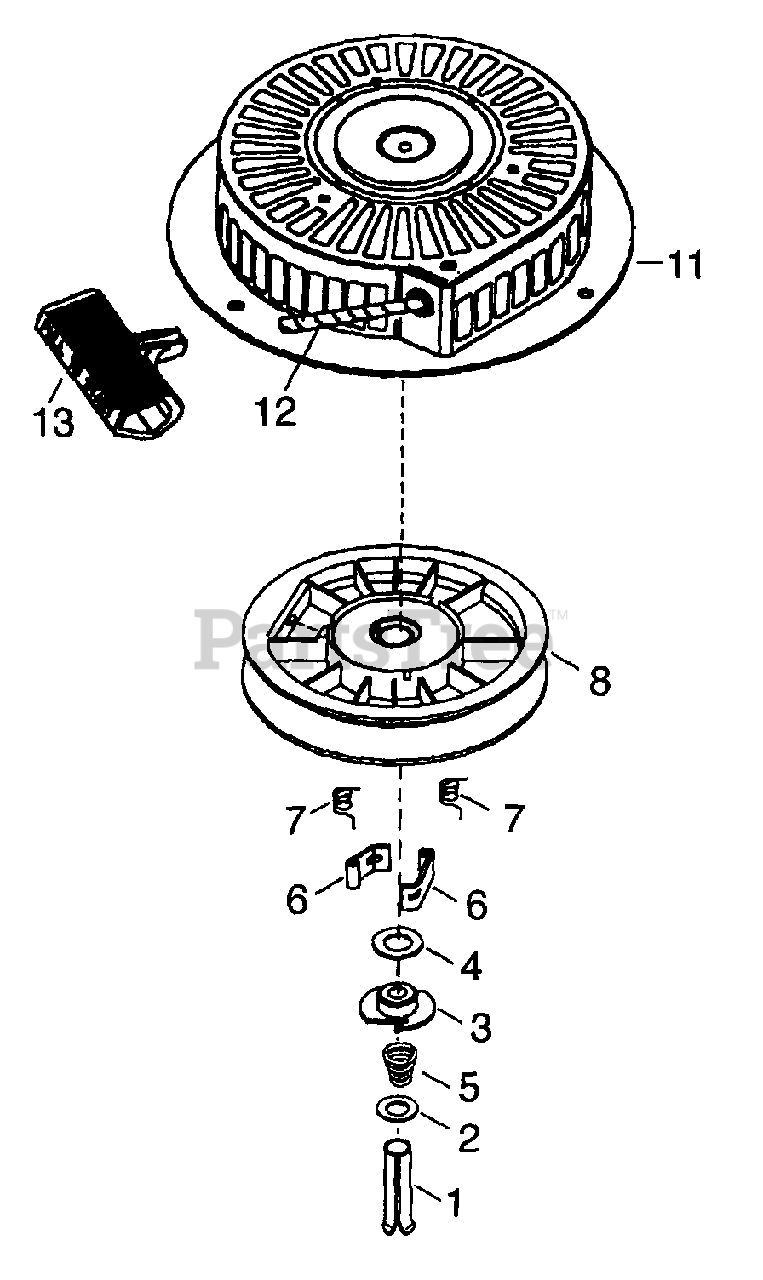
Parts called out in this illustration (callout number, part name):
1	Spring Pin
5	Brake Spring
6	Starter Dog
7	Dog Spring
8	Pulley & Rewind Spring Assy
11	Starter Housing Assy
12	Starter Rope
13	Starter Handle
